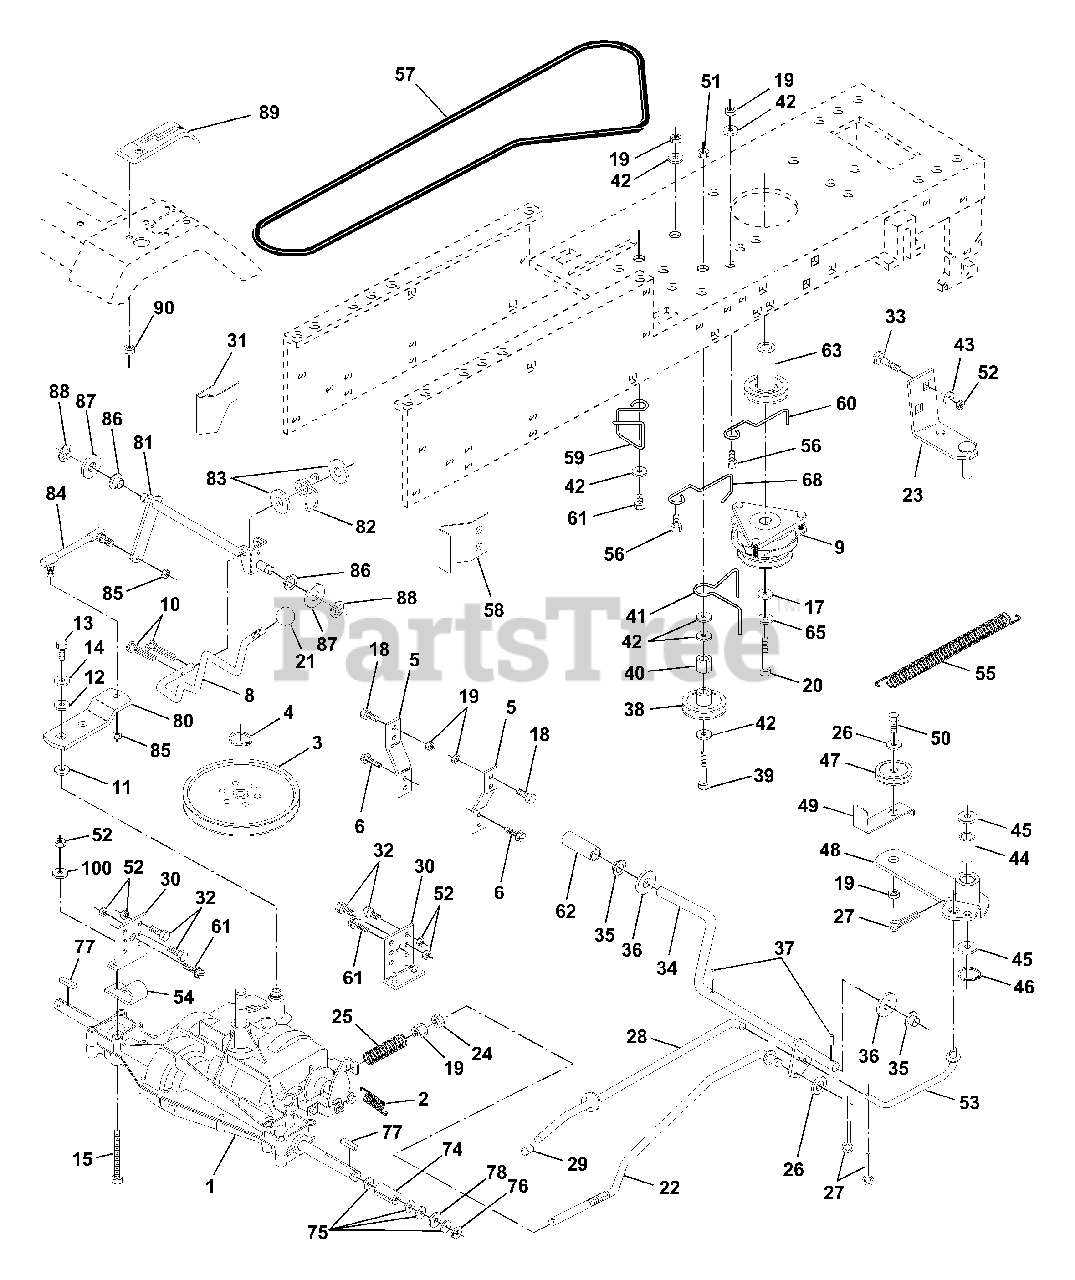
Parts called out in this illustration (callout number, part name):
1	Transaxle 6sp Dana LT Model #4360-96
2	Spring Return Brake
3	Pulley Transaxle 20" tires
4	Ring Retainer # 5100-62
5	Strap Torque 30 Degrees
6	Screw Thdrol 5/16-18 X 3/4 TYT
8	Rod Shifter
9	Clutch Electric
10	Pin Cotter 1/8 X 1 Cad
11	Washer Plate Shf 388 Sq Hole
12	Washer 15/32 X 3/4 X 16 Ga
13	Bolt 1/4-28 unf Gr 8 w/Patch
14	Washer Lock Hvy Helical 1/4
15	Bolt Fin Hex 5/16-18uncx 2 3/4
17	Washer 1-1/2 OD X 15/32 ID X .250
18	Bolt Fin Hex 3/8-16unc X 1 Gr. 5
19	Nut Lock 3/8-16 Unc
20	Bolt, Hex 7/16-20 x 4-1/4
21	Knob Duckhead 3/8-16unc Blk
22	Rod Brake Blk Zinc 27 326
23	Bracket Asm. Clutch
24	Nut Hex Jam 3/8-16 Unc
25	Spring Rod Brake 2 00 Zinc
26	Washer 13/32 X 13/16 X 16 Ga
27	Pin Cotter 1/8 X 3/4 Cad
28	Rod Brake Parking
29	Cap Brake Parking Black
30	Bracket Mtg Transaxle
31	Keeper Belt LH LT 14 Ga
32	Bolt Hex Hd 5/16-18unc X 3/4
33	Bolt, Carriage 5/16-18 x 3/4
34	Shaft Asm Pedal Foot
35	Bearing Nylon Blk 629 Id
36	Washer 21/32 X 1 X 16 Ga
37	Pin Roll 3/16 X 1"
38	Pulley Idler Flat
39	Bolt Fin Hex 3/8-16unc X 2-3/4
40	Spacer Split 395 X 59 Bzp
41	Keeper Belt Retainer
42	Washer 13/32 X 13/16 X 12 Ga
43	Washer 11/32 x 5/8 x 12 Ga.
44	Bearing Nyl 503 X 628 X 1 25
45	Washer Hardened
46	Ring Klip #t5304-50
47	Pulley Idler V Groove Plastic
48	Bellcrank Asm Clutch
49	Retainer Belt Style Spring
50	Bolt Hex Hd 3/8-16unc X 1-1/2
51	Nut Crownlock 3/8-16 Unc
52	Nut Crownlock 5/16 - 18
53	Link Clutch 7 66
54	Clip Fuel Line 13/32 Mtg. Hole
55	Spring Return Clutch 6 75
56	Bolt Fin Hex 3/8-16unc X 1-1/4
57	V-Belt Ground Drive 95 25 42"
58	Keeper Belt RH LT Pnt/zinc 16g
59	Keeper Belt Chassis Span Ctr
60	Keeper Belt Engine LH LT
61	Screw Thdrol 3/8-16x3/4 Ty-tt
62	Cover Pedal Premuim
63	Engine Pulley LT/YT
65	Washer Lock Hvy Hlcl Spr 7/16
68	Keeper Belt Engine BZP Zinc
74	Spacer Split
75	Washer 25/32 X 1 1/4 X 16 Ga
76	E-ring #5133-75
77	Key Square 2 0 X 1845/ 1865
78	Washer 25/32 X 1-5/8 X 16 Ga
80	Arm Shift Transaxle
81	Shaft Asm Cross 20"t 42" deck
82	Spring Torsion T/a
83	Washer 17/32 X 3/4 X 16 Ga
84	Rod Tie Shift Adj Ball
85	Nut Nylock 1/4-28
86	Bushing Rod Strg 629/632 Id
87	Washer 21/32 X 1-1/4 X 16 Ga
88	Ring Klip #5304-62
89	Console Shift 6sp W/ign LT
90	Nut Self-thd wsh-hd 1/4 zinc
100	Washer 11/32 x 3/4 x 16 Ga.
